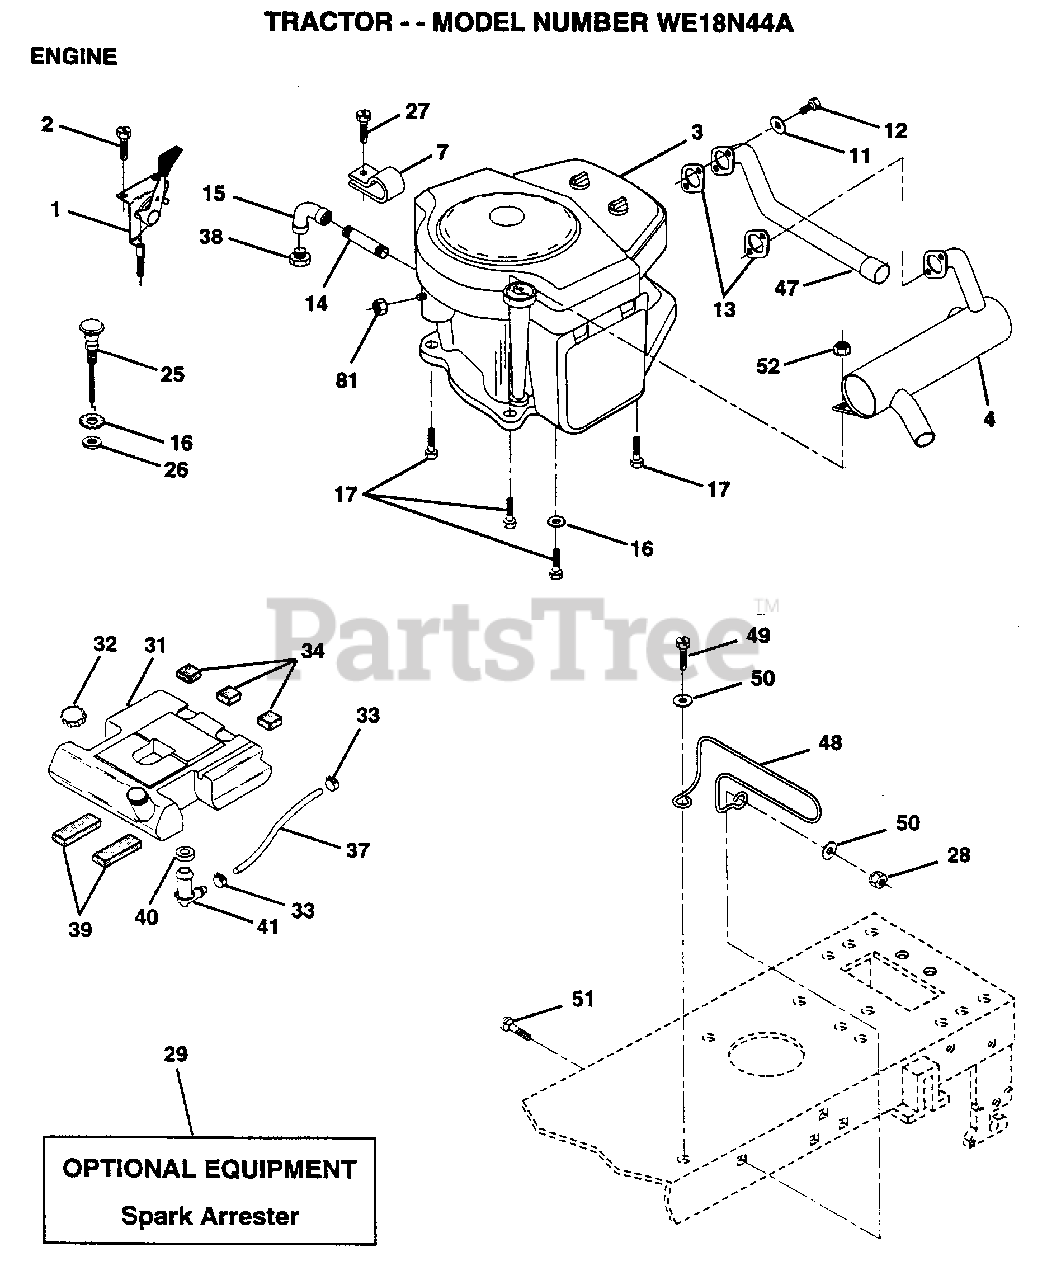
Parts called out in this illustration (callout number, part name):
1	CONTROL.THT.FLG.
2	SCREW LT
3	ENGINE B&S 18HP
7	CLAMP.TUBE.DBL.EN
11	LOCKWASHER
14	PIPE NIPPLE LT
15	ELBOW
16	LOCKWASHER
17	SCREW LT
25	"CONTROL.CHOKE.51"""
27	SCREW.10-24X1/2
32	CAP ASM FUEL
33	HOSE CLAMP
34	PAD-SPACER LT
37	FUEL LINE T
40	BUSHING OUTLET T
41	STEM.TANK.FUEL
47	EXHAUST TUBE T
48	MUFFLER GUARD
49	BOLT D
50	WASHER HYT
51	SCREW
52	NUT
81	NUT
